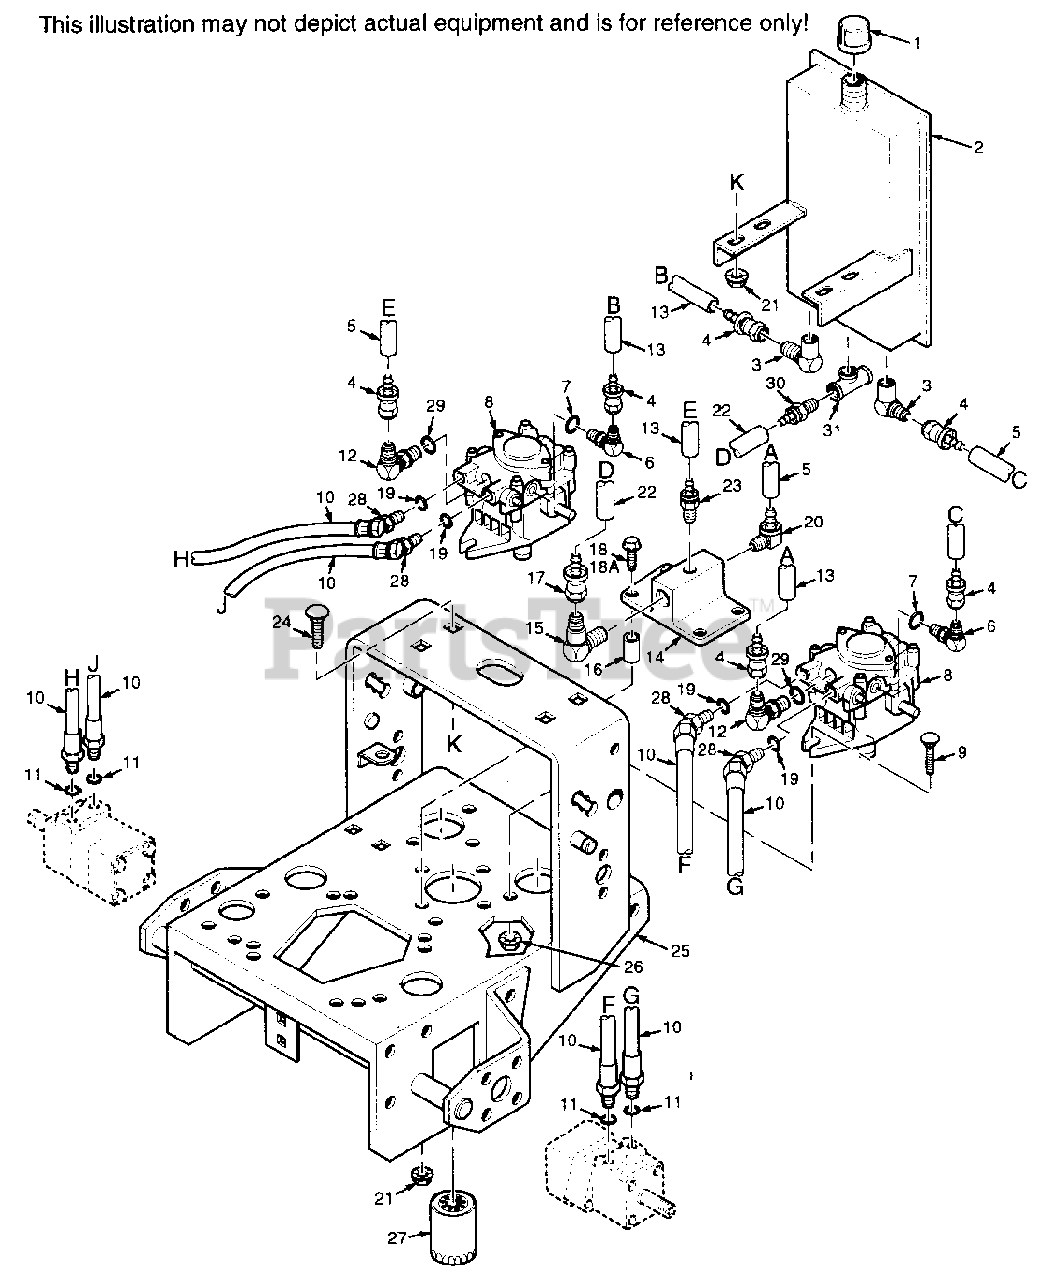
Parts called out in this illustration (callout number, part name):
1	CAP, OIL RESERVOIR
2	OIL RESERVOIR
3	ELBOW, 90 DEG. FEMALE 1/4 NPT TO 1/4 JIC MALE
4	COUPLING, 7/16-20 SAE FLARE SWIVEL TO 1/4"
5	HOSE, 1/4" ID, 12" LONG
6	ELBOW, 90 DEG. 7/16-20 JIC TO 9/16-18 "O"
7	O-RING
8	PUMP, SUNSTRAND BDP-10L117
10	HOSE, HOSE ONLY PUMP TO MOTOR(HOSE ONLY FOR
11	O-RING
12	ELBOW, 90 DEG. 7/16-20 UNC TO 7/16-20 O-RING
13	HOSE, 1/4" ID - 10" LONG
14	OIL FILTER BASE(INCLUDES ITEM 27)
15	ELBOW, 90 DEG. MALE 3/4-16 JIC TO 1/2" MALE
17	COUPLING, 3/4-16 SAE FLARE SWIVEL TO 1/2"
19	O-RING
20	ELBOW, 90 DEG. MALE 1/4 NPT TO 1/4 HOSE PUSH
21	NUT, 5/16-18 SERR. FL. HH
22	HOSE, 1/2" ID, 12" LONG
23	COUPLING, 1/4 STRAIGHT MALE NPT TO 1/4 HOSE
24	BOLT, 5/16-18 X 3/4, CARRIAGE
25	ENGINE DECK(16" WIDE)
26	NUT, 3/8-16, SERR. FL. HH
27	OIL FILTER
28	ELBOW, 45 DEG.
29	O-RING
30	COUPLING, 3/8 STRAIGHT MALE NPT TO 1/2 PUSH-
31	T-FITTING, 3/8 NPT
